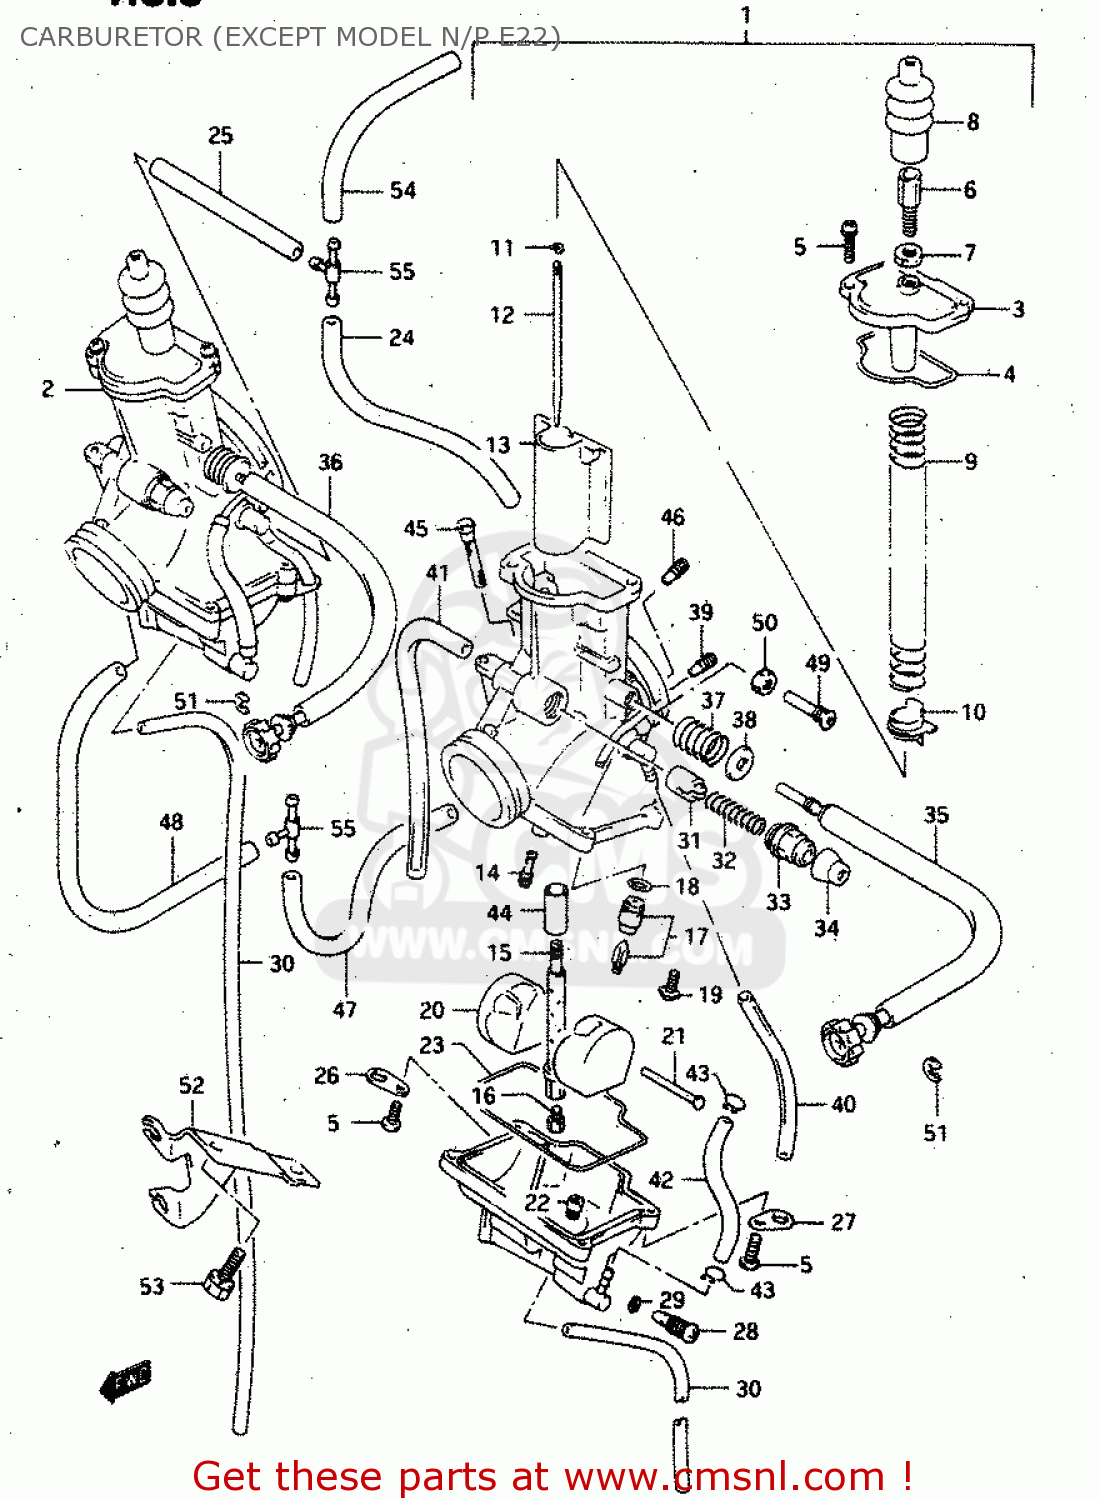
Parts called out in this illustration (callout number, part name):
1	CARBURETOR ASSY, LH
2	CARBURETOR ASSY, RH
3	CAP, TOP
4	O RING,TOP CAP
5	SCREW
6	ADJUSTER,CABLE
7	NUT
8	CAP,CABLE ADJUSTER
9	SPRING
10	RING
11	CLIP,NEEDLE
12	NEEDLE,JET
13	VALVE,PISTON(CA:1.5)
14	JET,PILOT 20
15	JET,NEEDLE(O-8)
16	JET,MAIN(270)
17	VALVE ASSY,NEEDLE
18	O-RING,NEEDLE VALVE
19	SCREW
20	FLOAT
21	PIN,FLOAT
22	JET(45)
23	GASKET,FLOAT CAHMBER (NAS)
24	HOSE(3.5X6.5X600)
25	HOSE(3.5X6.5X600)
26	PLATE,CARBURETOR
27	PLATE
28	PLUG,DRAIN
29	O RING
30	HOSE(3X5X650)
31	PLUNGER,STARTER
32	SPRING
33	HOLDER,GUIDE
34	CAP
35	ADJUSTER,THROTTLE STOP
36	ADJUSTER,THROTTLE STOP
37	SPRING
38	WASHER
39	JET,AIR(1.3)
40	HOSE(3X5X650)
41	HOSE(4X7X600)
42	HOSE SET
43	CLIP
44	RING
45	FILTER
46	JET,AIR(0.6)
47	HOSE(3.5X6.5X600)
48	HOSE(3.5X6.5X600)
49	SCREW,ADJUSTER
50	NUT
51	E RING
52	BRACKET,ADJUSTER
53	BOLT
54	HOSE(3.5X6.5X600)
55	3-WAY
